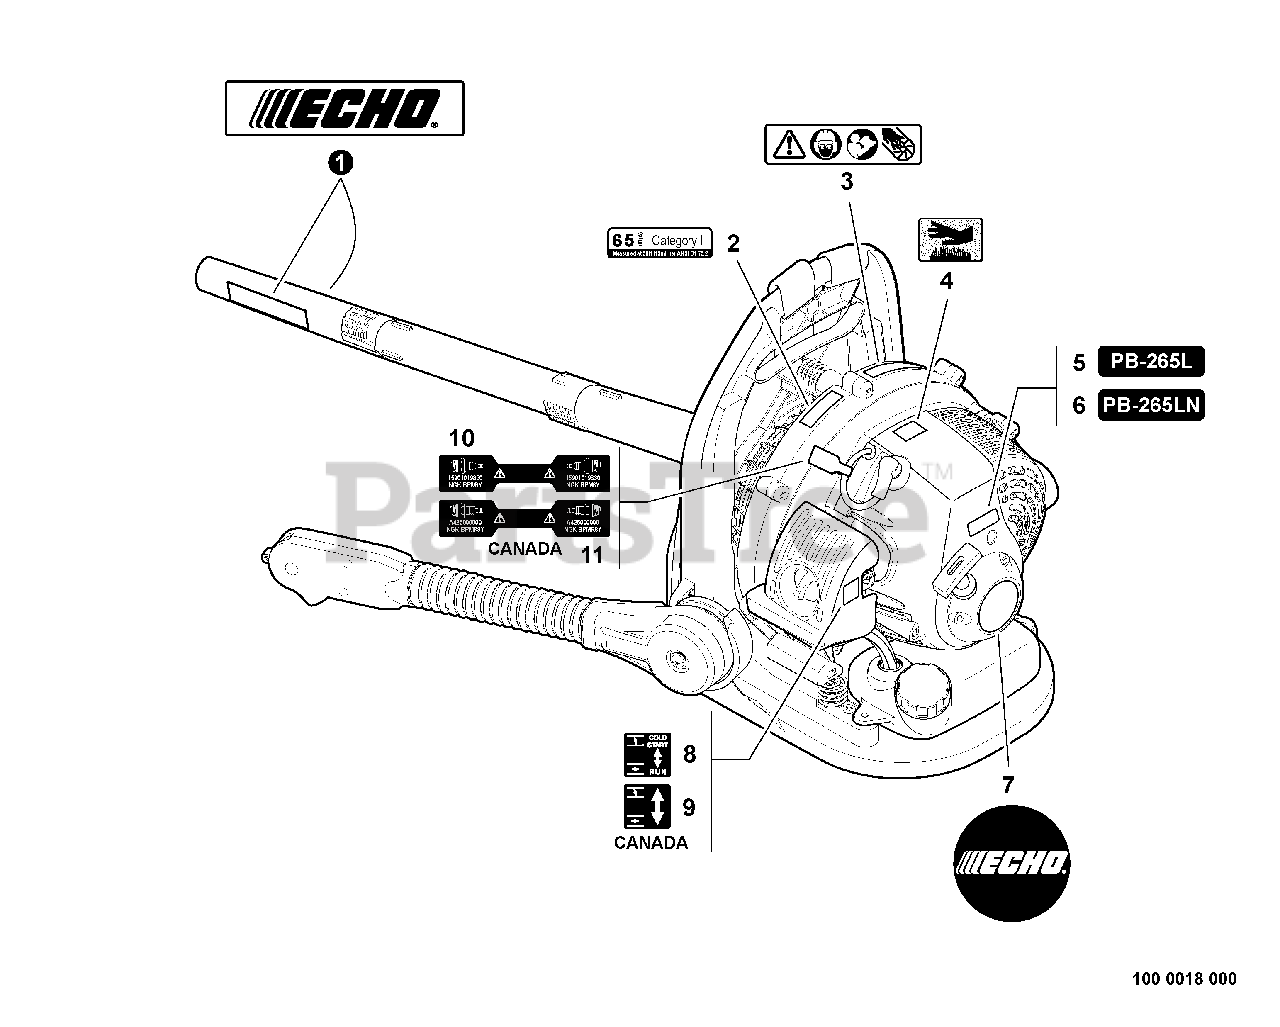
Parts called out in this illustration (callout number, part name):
1	LABEL - ECHO
2	LABEL - NOISE 65dB(A) CAT I
3	LABEL - CAUTION
4	LABEL - HOT SURFACE
5	LABEL - MODEL PB-265L
6	LABEL - MODEL PB-265LN
7	LABEL - ECHO
8	LABEL - CHOKE
9	LABEL - CHOKE
10	LABEL - SPARK PLUG -- BPM-8Y
11	LABEL - SPARK PLUG -- BPMR-8Y
